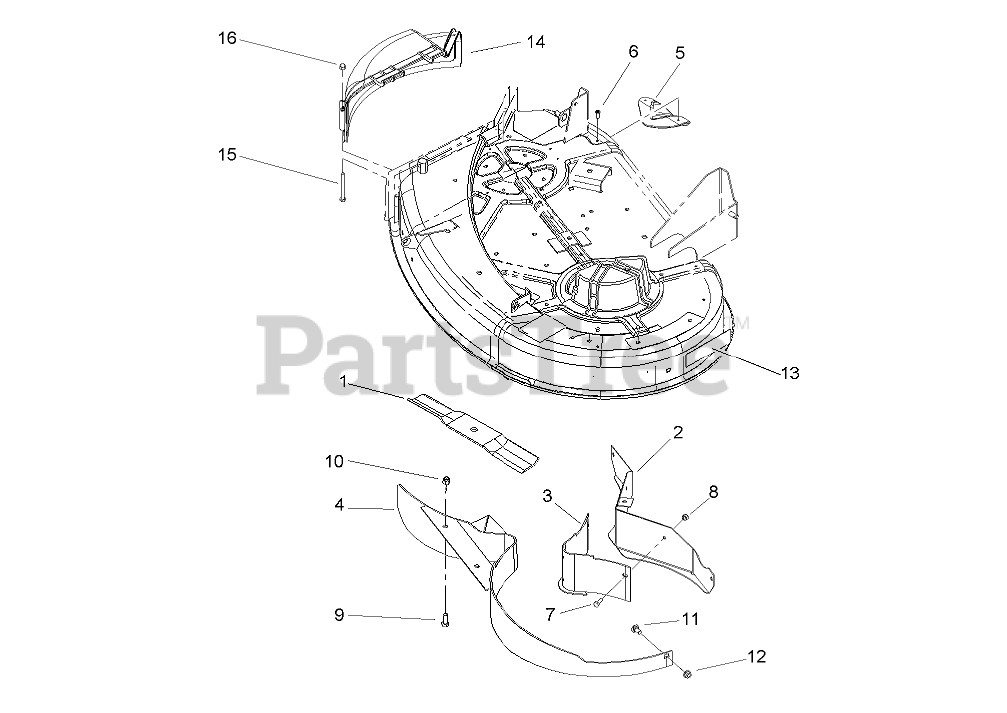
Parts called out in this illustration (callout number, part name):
2	BAFFLE-REAR
3	BAFFLE ASM
4	BAFFLE ASM
5	PLATE-KICKER
6	SCREW-PPH
7	SCREW-HH
8	NUT-LOCK, NI
9	SCREW-HH
10	NUT-LOCK, NI
11	BOLT-CARR
12	NUT-HF
14	COVER-RECYCLER
15	SCREW-HH
16	NUT-CAP
